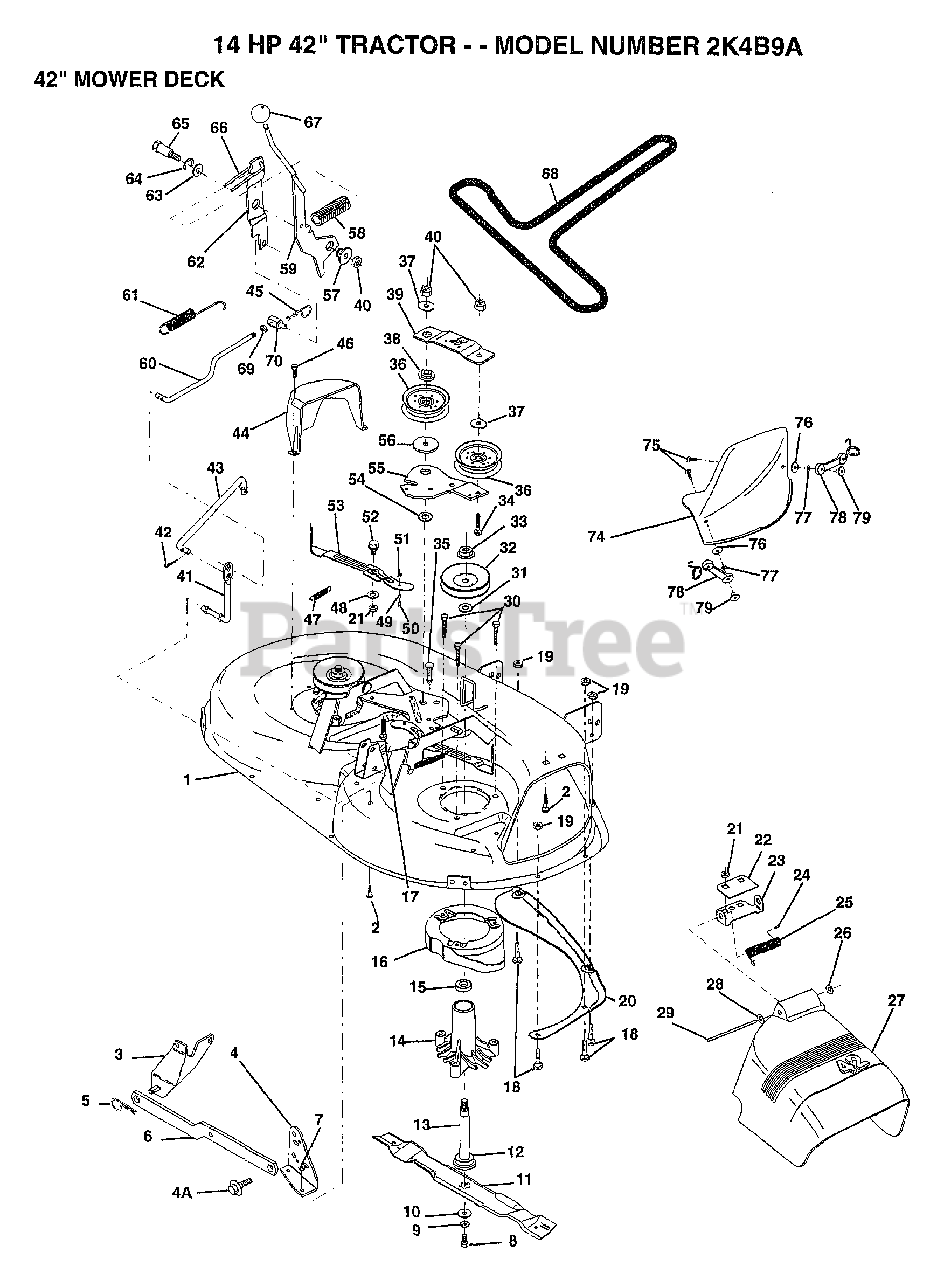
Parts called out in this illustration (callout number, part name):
2	BOLT
3	BRKT ASM SWAY BAR
4	BRKT DECK SW BAR
4A	BOLT SHD 5/16-18
7	NUT
8	BLADE BOLT
10	WASHER.HARD.BLADE
11	"BLADE.42"" MULCHER"
12	BEARING.BALL
14	HSG ASM MANDREL
15	BEARING
17	BOLT CARRIAGE
18	BOLT
19	NUT
22	STIFFENER BRKT
23	DEFLECTOR BRKT
24	CAP-SLEEVE LT
25	SPRING TORSION
26	NUT PUSH M
27	DEFLECTOR.SHIELD
28	WASHER
29	HINGE ROD
34	BOLT
35	XMAS TREE FASTNER
36	FLAT IDLER PULLEY
37	WASHER GT
38	RETAINER SPACER
39	IDLER ARM STIFF
41	PIVOT ROD
43	CLUTCH ROD SECOND
44	GUARD MAND LH BLK
45	RETAINER M
46	SCREW.1/4-20X5/8
47	SPRING EXTENSION
48	HARD SMALL WASHER
50	SHOULDER BOLT
51	LOCKNUT
52	BOLT.SHLD.5/16-18
53	BRAKE PAD ARM ASM
54	HARDENED WASHER
55	IDLER ARM
56	SPACER RETAINER
57	BUSHING
59	CLUTCH ARM PRI AS
61	RETURN SPRING
62	CLUTCH ARM SECOND
63	WASHER
64	RING
65	SHOULDER BOLT
66	SPRING KEEPER
67	KNOB T(3/8 HOLE)
68	BELT-V.92.4.MWR
69	NUT
70	TRUNION
74	"COVER.MULCH.42"""
75	SCREW
76	WASHER #10
77	LOCKWASHER
79	WELDNUT
